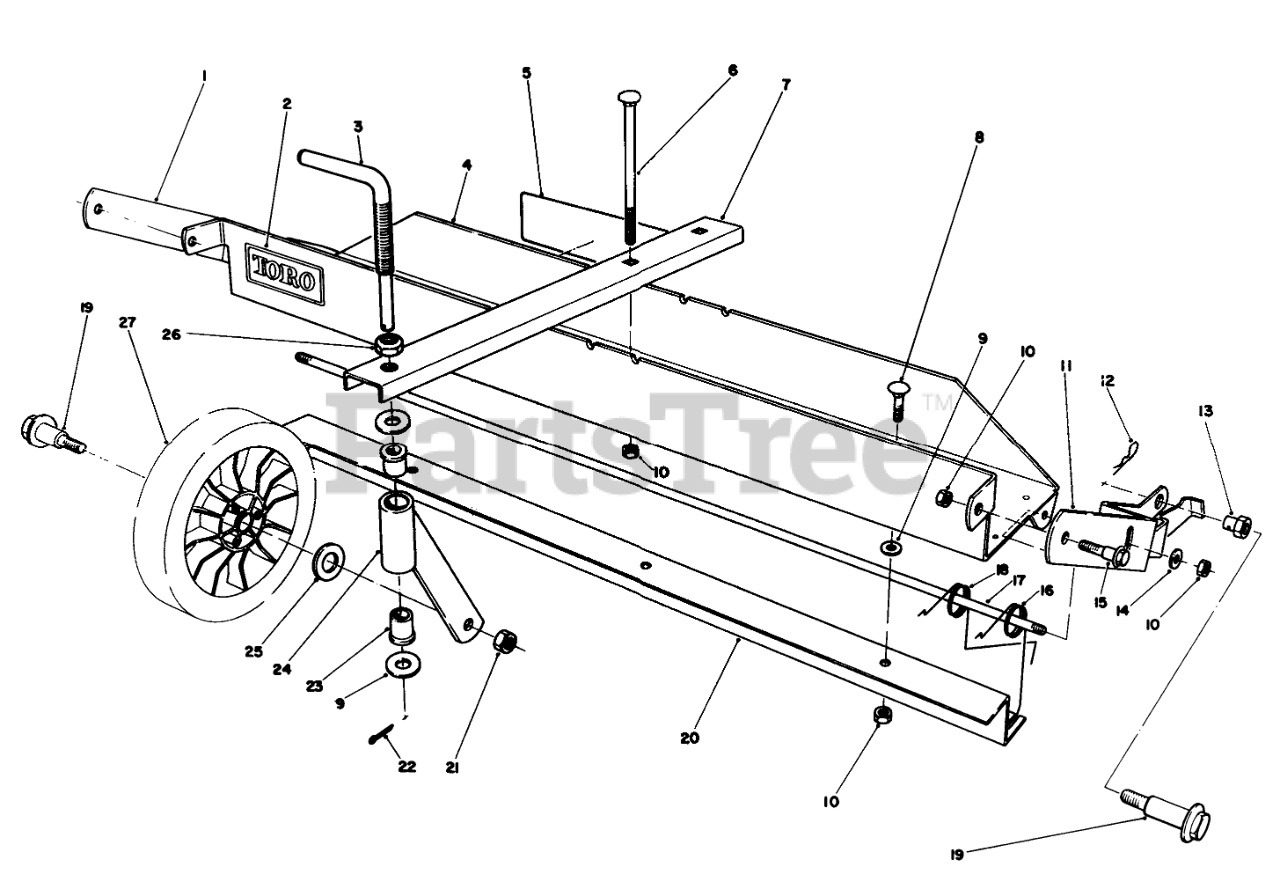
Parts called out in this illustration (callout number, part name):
1	Frame R.H.
2	Decal-Toro
3	CASTOR ADJ ROD
4	Frame-Main (Incl. Ref. #2 & 5)
5	Decal-Instruction
6	SCREW-CARR
7	Castor Frame
8	BOLT-CARR
9	WASHER-PLAIN
10	NUT-HEX, SIDE DEFORM
11	LH MTG FRAME
12	PIN-COTTER, HAIR
13	PIVOT NUT
14	WASHER-FLAT
15	BOLT-SHOULDER
16	DETHATCHER SPRING
17	SPRING SUPPORT ROD
18	DETHATCHER SPRING
19	BOLT-WHEEL
20	SPRING GUIDE STRAP
21	NUT-LOCK
22	PIN-COTTER
23	FLANGE BUSHING
24	Castor Tube & Support
25	WASHER
26	NUT-JAM
27	Wheel Assembly
